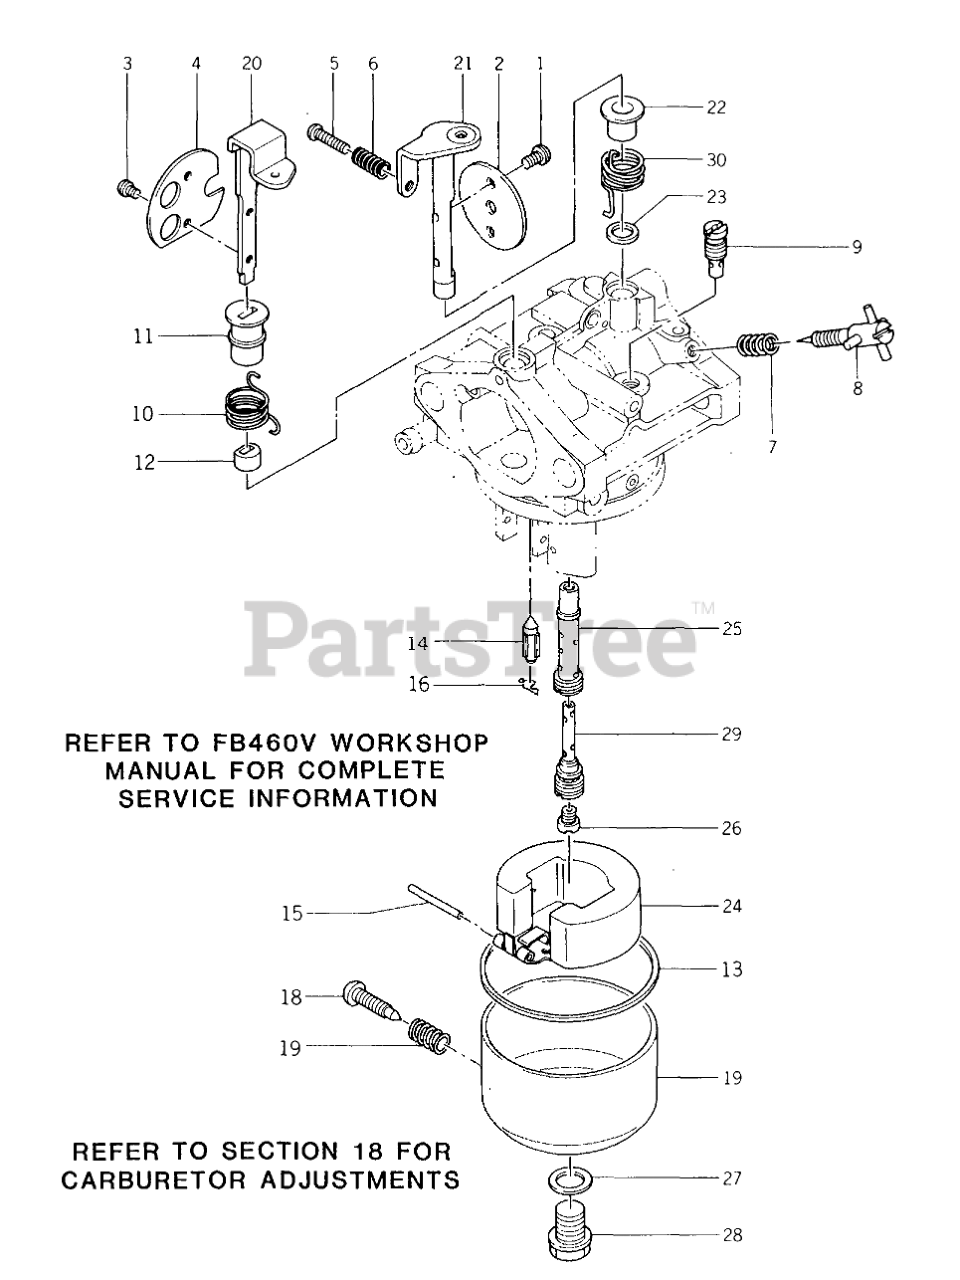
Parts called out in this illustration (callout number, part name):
2	Throttle Valve (#120)
4	Choke Valve
9	Pilot Jet (#62.5)
12	Ring
13	Gasket
14	Valve-Float
15	Pin
17	Float Chamber Assy (includes items 18 & 19)
18	Screw
20	Shaft-Choke
21	Shaft-Throttle
28	Bolt
29	Pipe-Bleed
31	Carburetor Gasket Set
